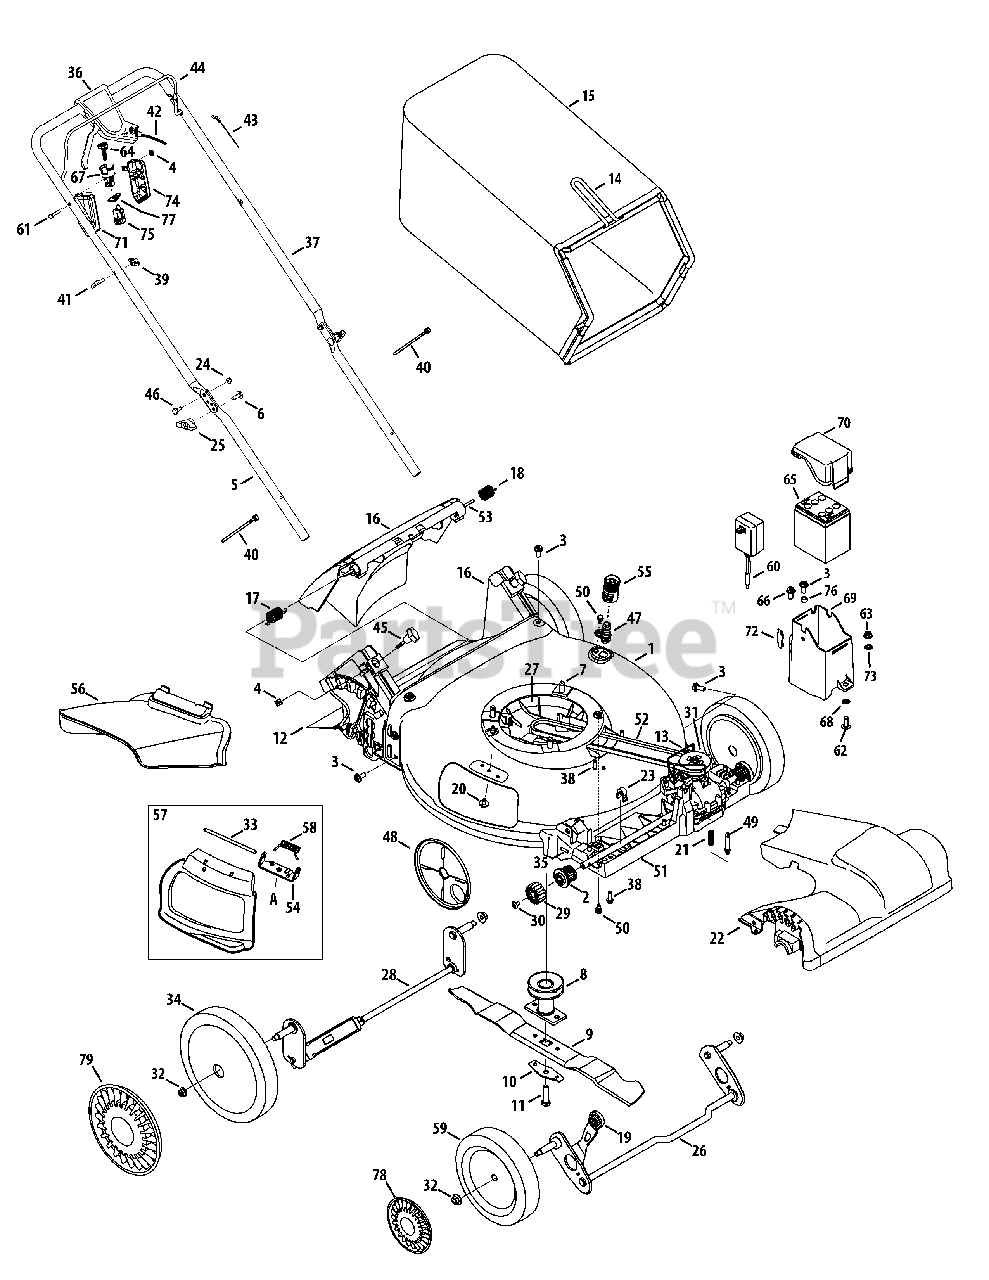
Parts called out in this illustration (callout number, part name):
1	Deck , 21"
2	Bearing Assembly
3	Screw, 5/16-14 x .750
4	Nut, Sq., 1/4-20
5	Lower Handle
6	Carriage Screw ,5/16-18
7	Screw, 3/8-16 x 1.00
8	Blade Adapter (159cc)
9	Mulching Blade
10	Blade Bell Support
11	Screw, 3/8-24 x 1.50
12	Trailing Shield
13	Transmission Wire
14	Grass Catcher Frame
15	Grass Bag
16	Rear Discharge Door Assembly
17	Torsion Spring - RH
18	Torsion Spring - LH
19	Adjustment Lever Knob
20	Screw, 1/4-20 x .500
21	Compression Spring
22	Front Cover
23	Front Axle Clip
24	Nut, Flange Lock, 1/4-20
25	Wing Knob
26	Front Axle Assembly
27	Engine Baffle
28	Rear Axle Assembly
29	Spur Gear, 14T - RH
29	Spur Gear, 14T - LH
30	Screw, 1/4-20 x .390
31	Transmission Assembly
32	Flange Lock Nut, 3/8-16
33	Front Wheel,
34	Rear Wheel, 11",
35	Dowel Pin
36	Control Lever Assembly
38	Screw, 1/4-15 x .750
40	Cable Tie
41	Rope Guide
42	Drive Cable
43	Control Cable 37.58"
44	Blade Control
45	Wing Nut
46	Sldr. Screw, .375 x .126 x 1/4-20
47	Water Nozzle
48	Wheel Dust Cover
49	Spring Body
50	Scr., Shldr., 1/4-20 x .50
51	Lower Tray
52	V-Belt
53	Pivot Rod
54	Chute Deflector Bracket
55	Water Nozzle Adapter
56	Side Discharge Chute
57	Mulch Plug
58	Torsion Spring
59	Hinge Pin
60	Battery Charger
61	Screw, 1/4-20 x 1.75
62	Bolt, Carr., 5/16-18 x 1.00
63	Nut, Hexlk, 5/16-18
64	Key
65	Battery
66	Scr., Sldr., 5/16-14 x .972
67	Key Switch
68	Speed Nut
69	Battery Housing
70	Battery Housing Top
71	Electric Start Housing, RH
72	Lid Seal
73	Washer, Bell, .340 x .872 x .080
74	Electric Start Housing, LH
75	Plunger Switch
76	Spacer, .340 x .460 x .246
77	Retainer Bracket
78	Hubcap
79	Hubcap
